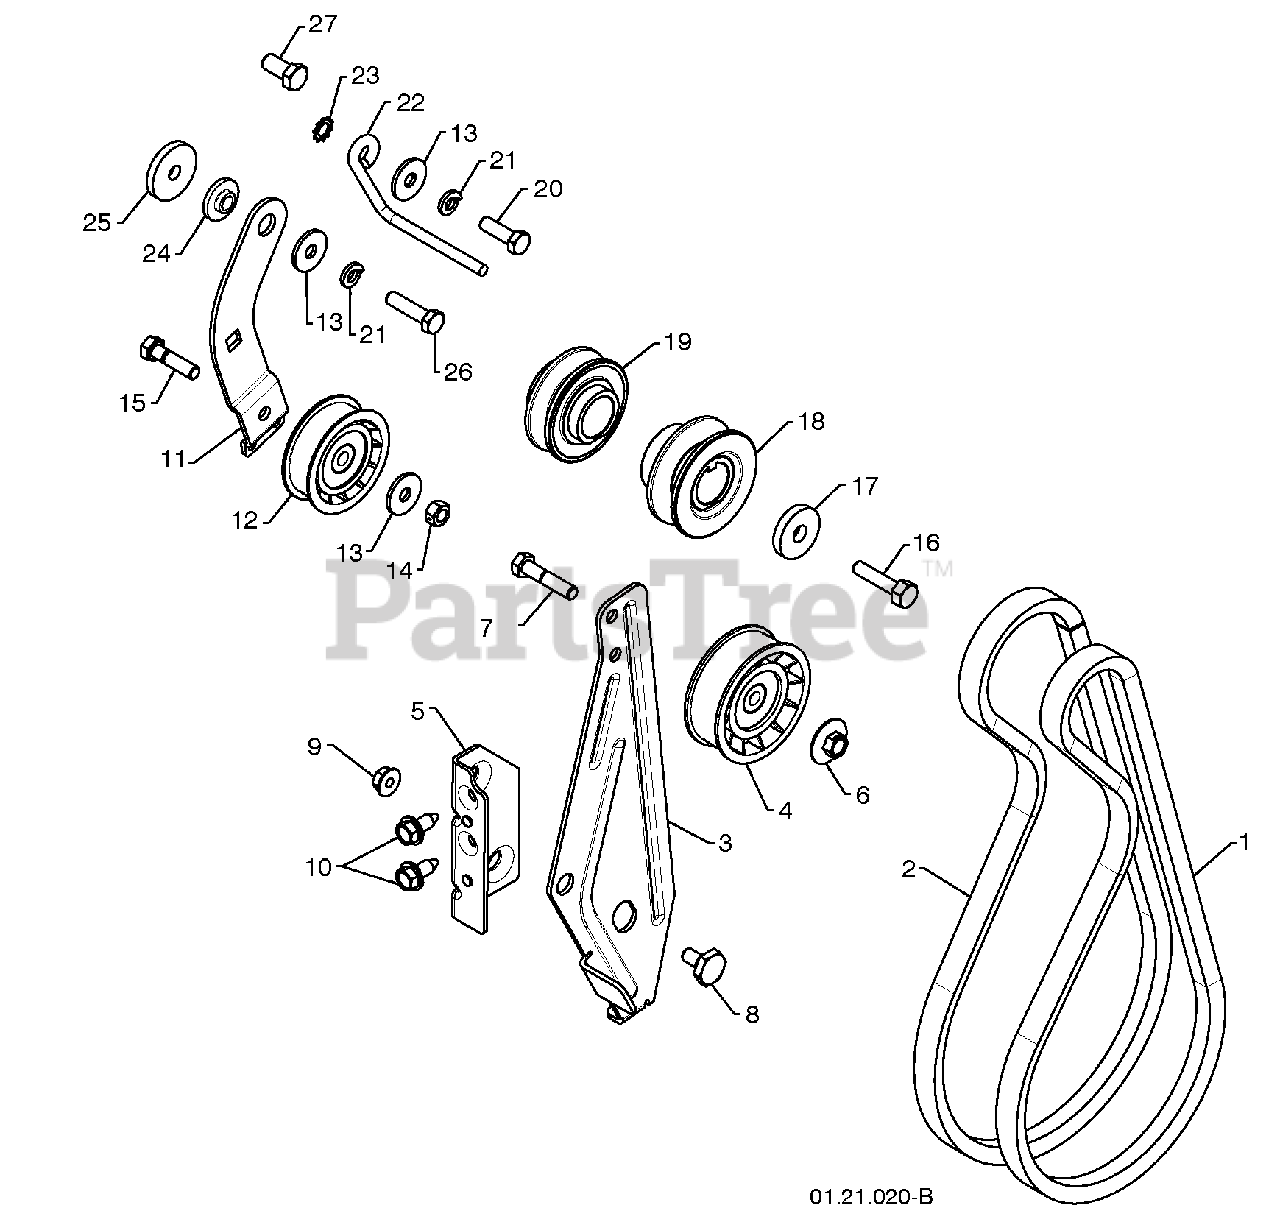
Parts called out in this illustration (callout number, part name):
1	IMPELLER BELT
2	TRACTION BELT
3	IDLER ARM BRACKET
4	IDLER PULLEY
6	NUT 5/16-18
7	SCREW 5/16-18 X 1.50
8	SHOULDER BOLT 5/16-18 X .50
9	NUT 5/16-18 LOCK
10	SCREW 5/16-18 X .625
11	TRACTION IDLER BRACKET
12	TRACTION PULLEY
13	WASHER
14	NUT 5/16-18
15	SCREW 5/16-18 X 1.25
16	SCREW 3/8-24 X 1 .375
18	PULLEY ENG IMPELLER
19	PULLEY ENG TRACTION
20	SCREW 5/16-24 X 1.00
21	LOCKWASHER 5/16
22	BELT GUIDE
23	LOCKWASHER 5/16
24	IDLER BUSHING
25	WASHER
26	SCREW 5/16-24 X 1.25
27	SCREW 3/8-16 X .750
